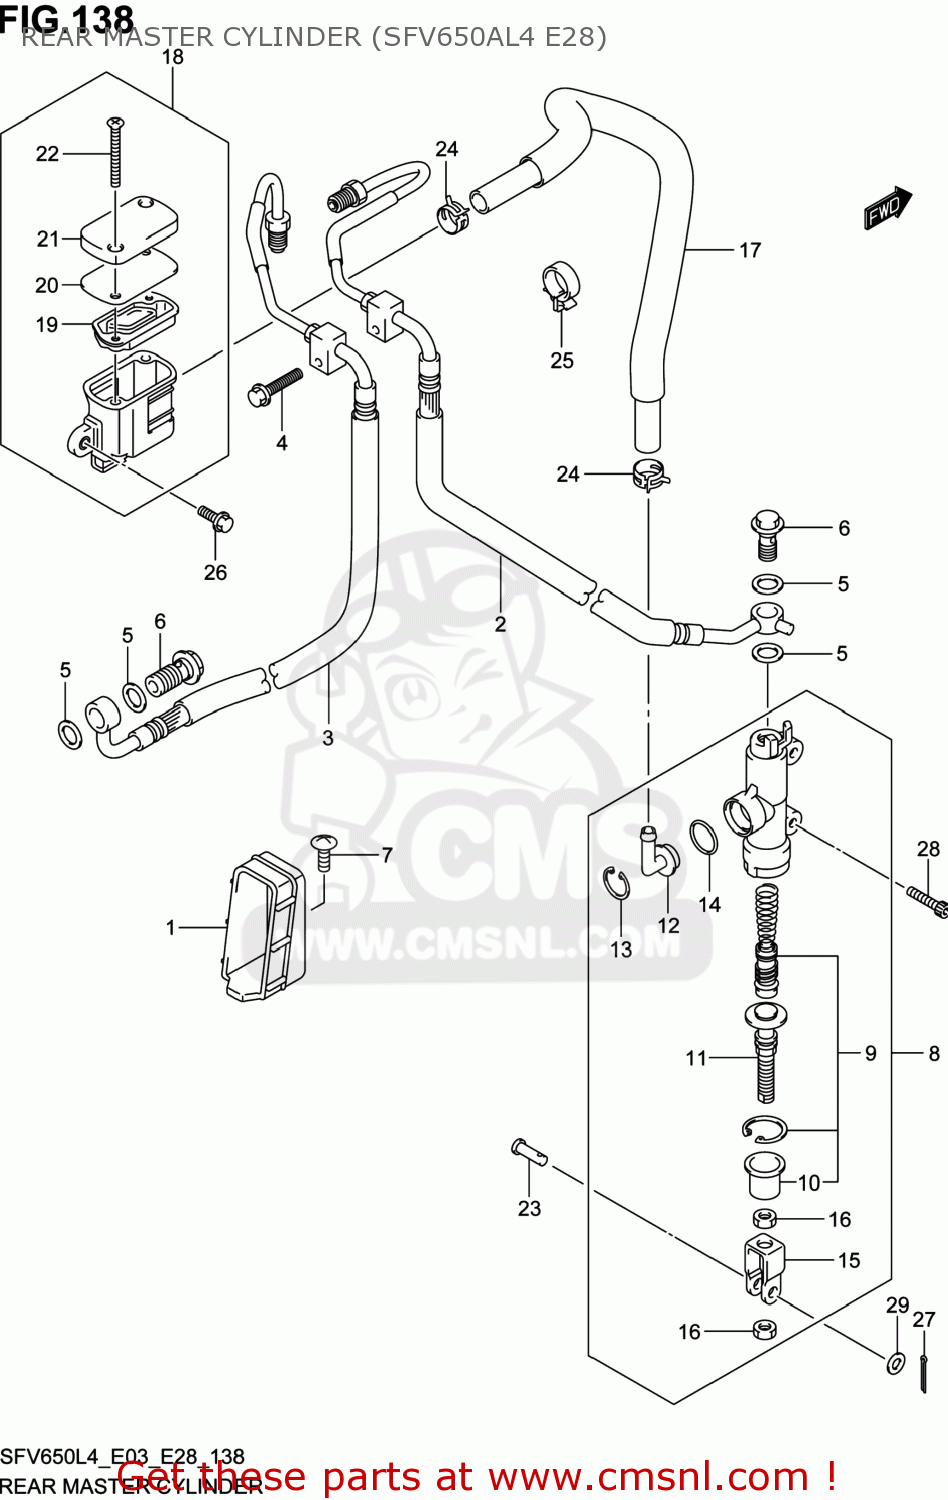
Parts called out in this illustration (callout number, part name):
1	GUIDE,RR BRAKE HOSE
2	HOSE ASSY,RR BRAKE NO.1
3	HOSE ASSY,RR BRAKE NO.2
4	BOLT
5	WASHER(10X15X1.5)
6	BOLT UNION
7	SCREW
8	CYLINDER ASSY,RR MASTER
9	PISTON/CUP SET
10	BOOT
11	ROD,PUSH
12	CONNECTOR
13	CIRCLIP
14	O RING
15	YOKE
16	NUT
17	HOSE,RR RESERVOIR TANK
18	TANK ASSY,RESERVOIR
19	DIAPHRAGM
20	PLATE,DIAPHRAGM
21	CAP
22	SCREW
23	PIN(6X18.2)
24	CLIP
25	CLAMP
26	BOLT
27	PIN
28	BOLT
29	WASHER
